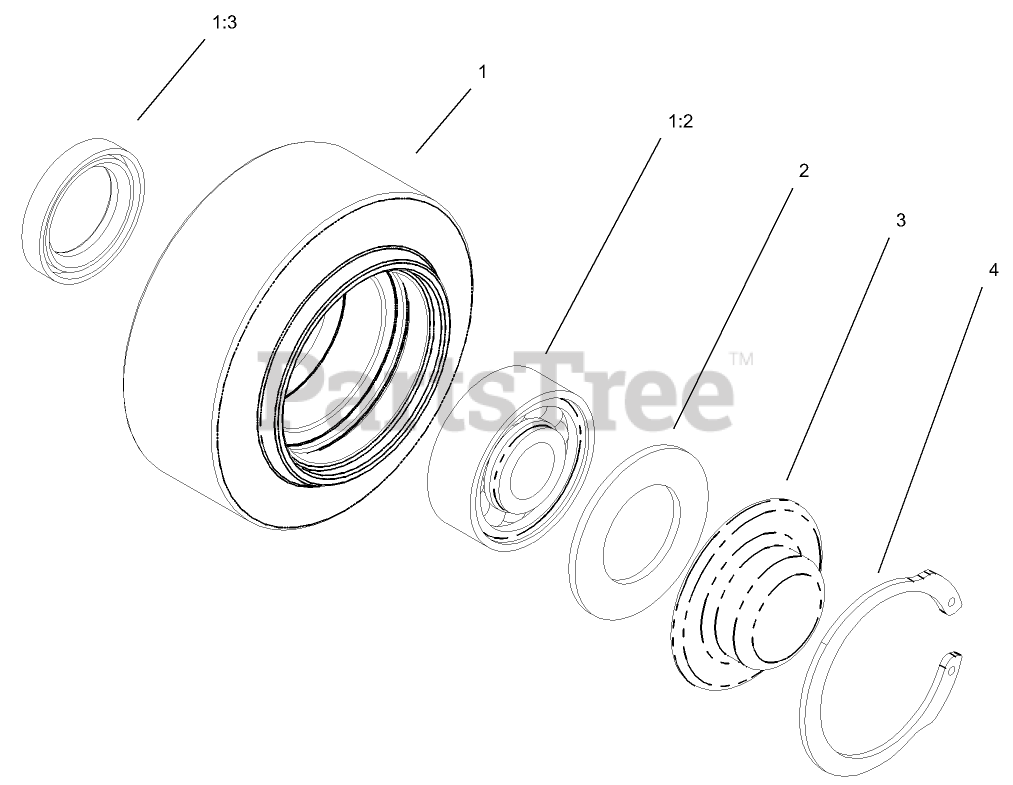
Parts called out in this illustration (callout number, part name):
1	Road Wheel ASM
1:2	BEARING
1:3	SEAL-OIL
2	Gasket-Bogie
3	CAP-WHEEL, BEARING
4	RING-SNAP, INTERNAL
